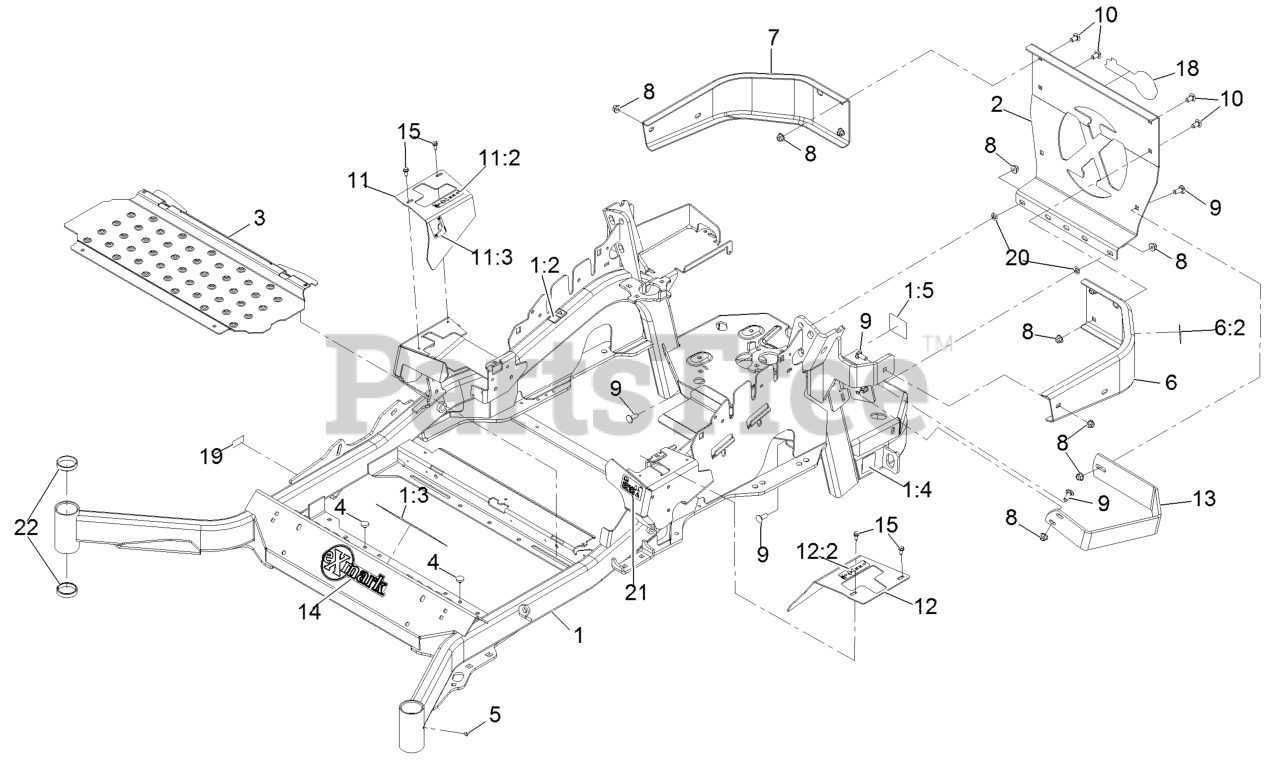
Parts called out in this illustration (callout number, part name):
1	Mainframe ASM
1:2	Decal-Warning, Hot Surface
1:3	Decal-Danger
1:4	Decal-Hazard, Pinched Finger
1:5	Decal-Spark Arrester
2	Plate,Rear Guard
6	LH Bumper ASM
6:2	Decal-Warning, Hot Surface
7	Bumper-RH
8	Nut-Nyloc 3/8-16 Flg
9	Bolt-Carriage 3/8-16 X 1
10	Bolt-Carriage 3/8-16 X 3/4
11	RH Motion Control Cover ASM
11:2	Decal-Control, Motion
11:3	Decal-Park Brake, Ce
12	LH Motion Control Cover ASM
12:2	Decal-Control, Motion
13	Guard-Muffler
14	Decal-Exmark Logo
15	Screw-HWH 1/4-20 X .62
18	Decal-Exmark Logo
19	Decal-Patent
20	Nut-Push 3/8-16
21	Decal-Fuel Fill, Ce
22	Cup-Bearing Tapered Roller
